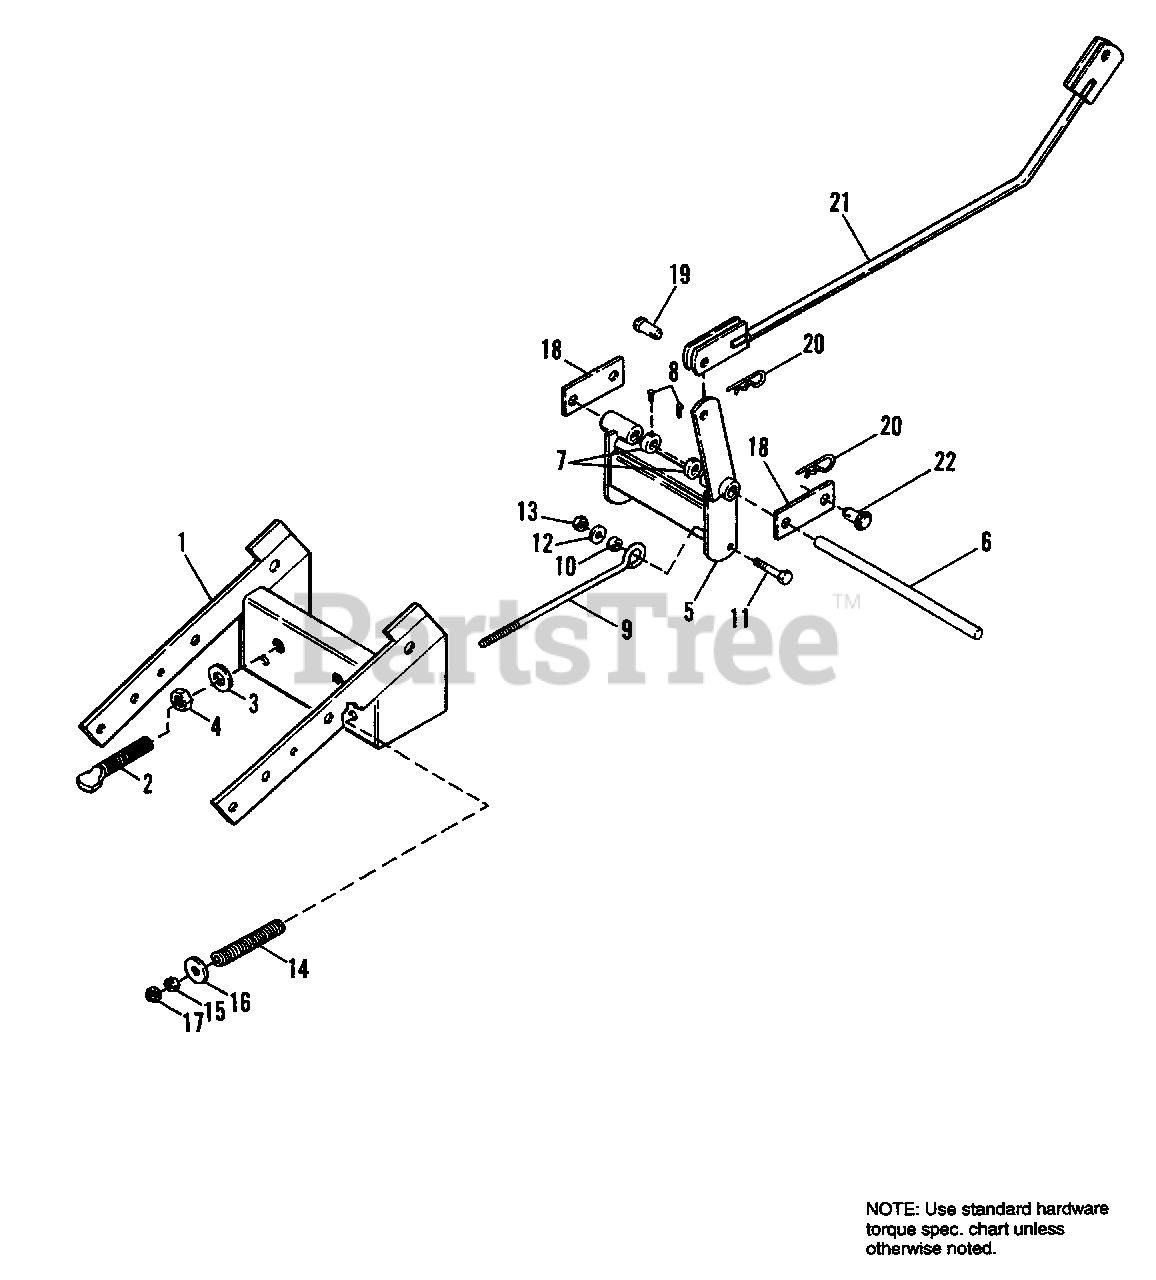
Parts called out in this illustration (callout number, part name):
1	HITCH ASSY., Blower
3	LOCKWASHER, 3/4 Std.
4	NUT, Hex, 3/4-10
5	HITCH ASSY.
6	SHAFT, Inner
7	SET COLLAR
8	SET SCREW, Sq. Hd. 5/16-18 x 1/2
11	CAPSCREW, Hex Hd., 5/8-11 x 2
12	WASHER, Plain, 41/64 x 1-3/4
13	NUT, Hex, Centerlock, 5/8-11
14	SPRING, Compression
15	NUT, Hex, 3/8-16
16	WASHER, 3/8 x 1-3/4 x 1/4
17	NUT, Hex, Jam, 3/8-16
19	PIN, Clevis
20	CLIP, Hair Pin, 1/8 x 2-9/16
21	LIFT ROD ASSY.
22	PIN ASSY.
